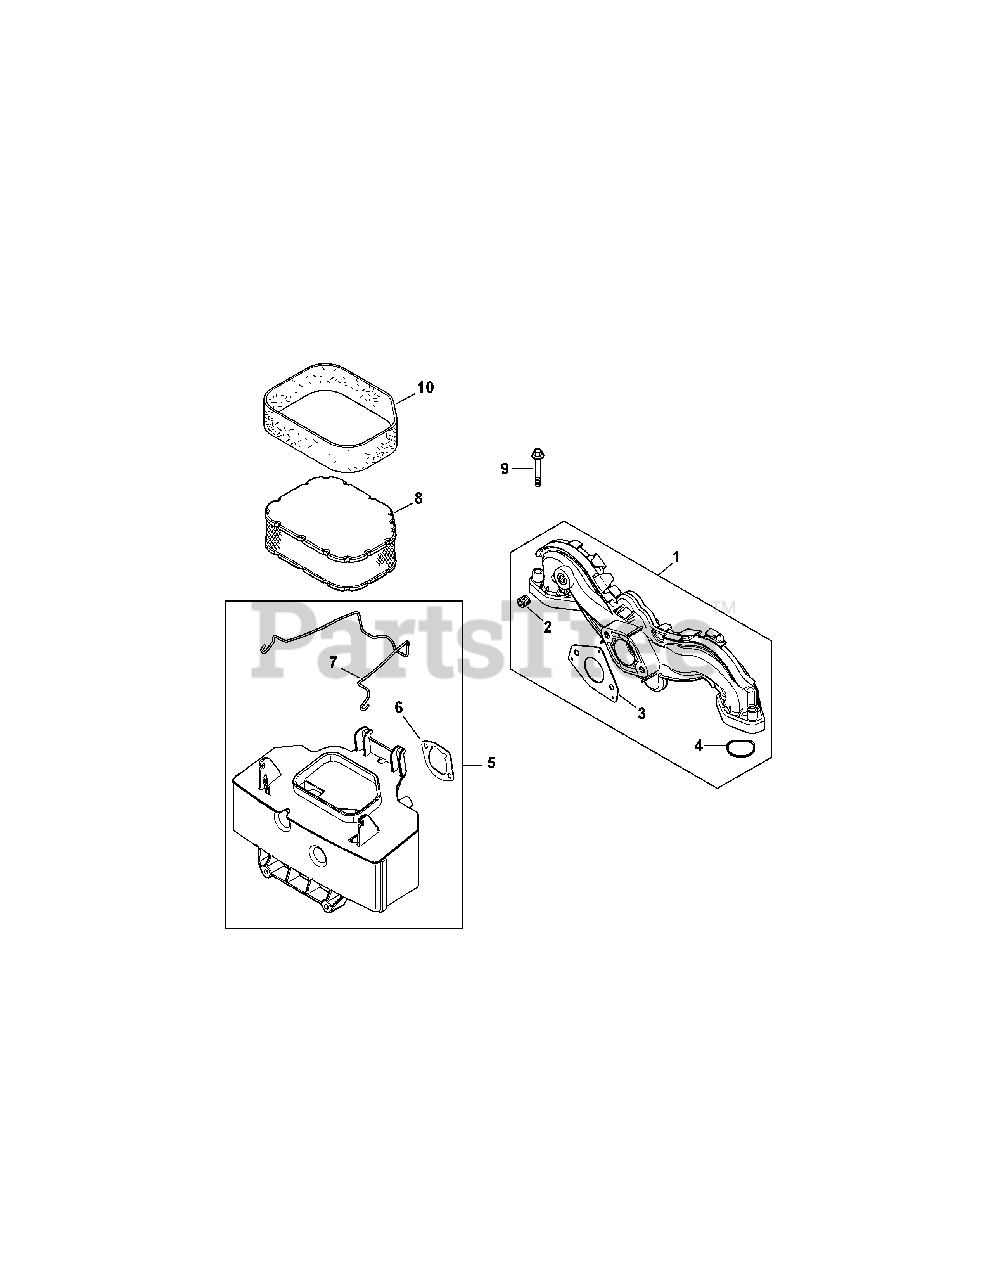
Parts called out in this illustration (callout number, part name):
1	Intake Manifold Kit (Inc. 2-4)
2	Carburetor Gasket
3	Intake Port O-Ring
4	Ctsk. Pipe Plug, 1/8
5	Air Cleaner Base Kit (Inc. 5 & 6)
6	Air Cleaner Base Gasket
7	Air Cleaner Element Latch
8	Air Filter Element
9	Flg. Screw, M6 x 1.0 x 40
10	Pre-Cleaner Element
